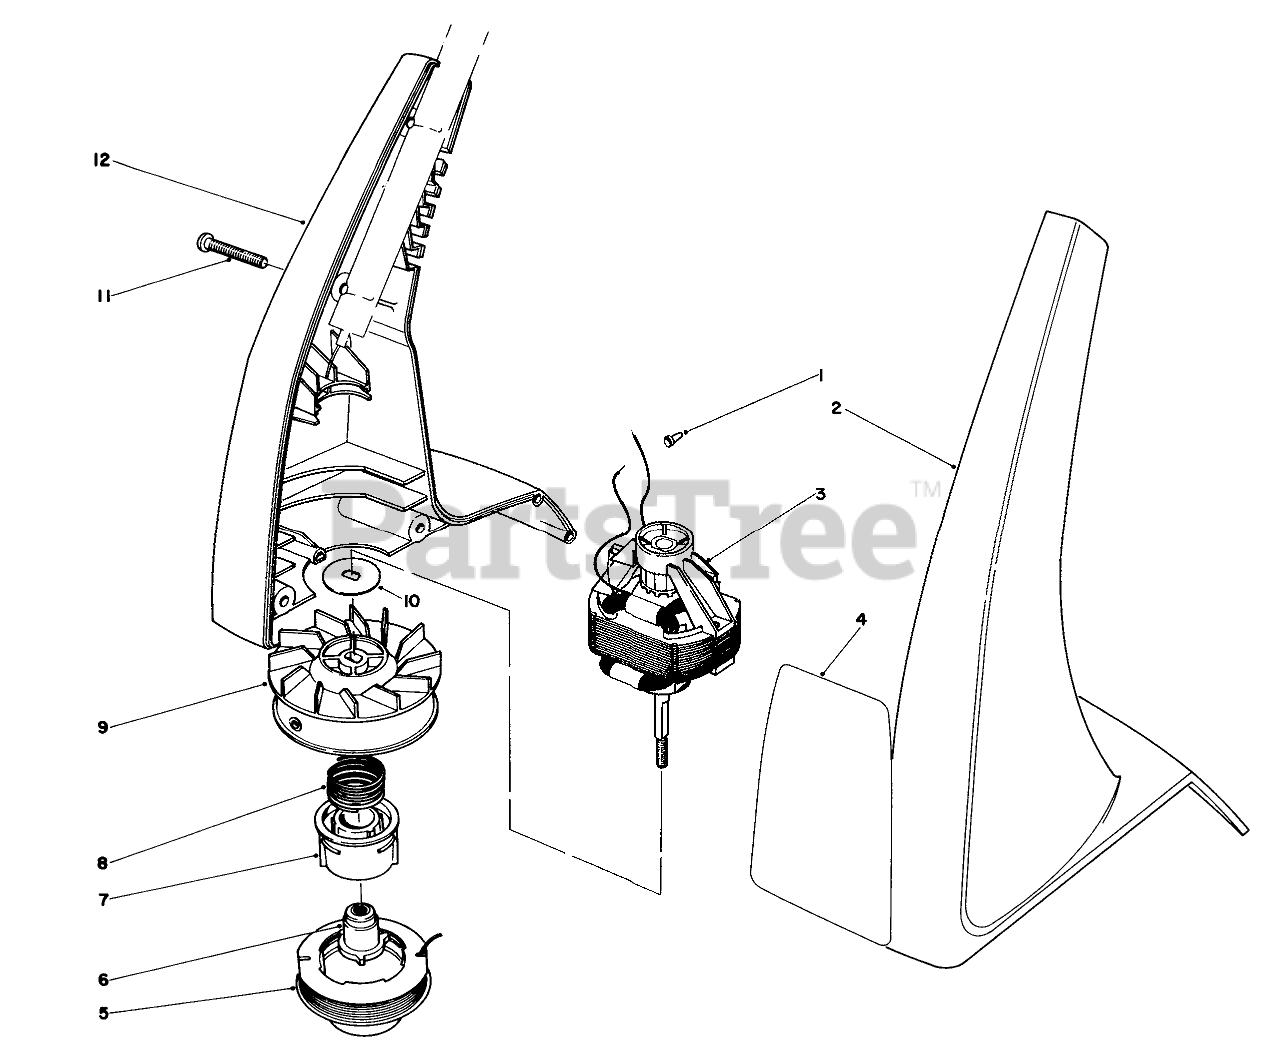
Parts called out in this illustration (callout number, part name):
1	CONNECTOR WIRE JOINT
2	L.H. HOUSING, 910
3	MOTOR, 910 TRIMMER
4	910 DECAL
5	Prewound Spool
6	DRIVER
7	CORE - SPOOL
8	Spring
9	Drum w/Eyelet
10	MOTOR WASHER
11	Screw
12	Housing-R.H.
